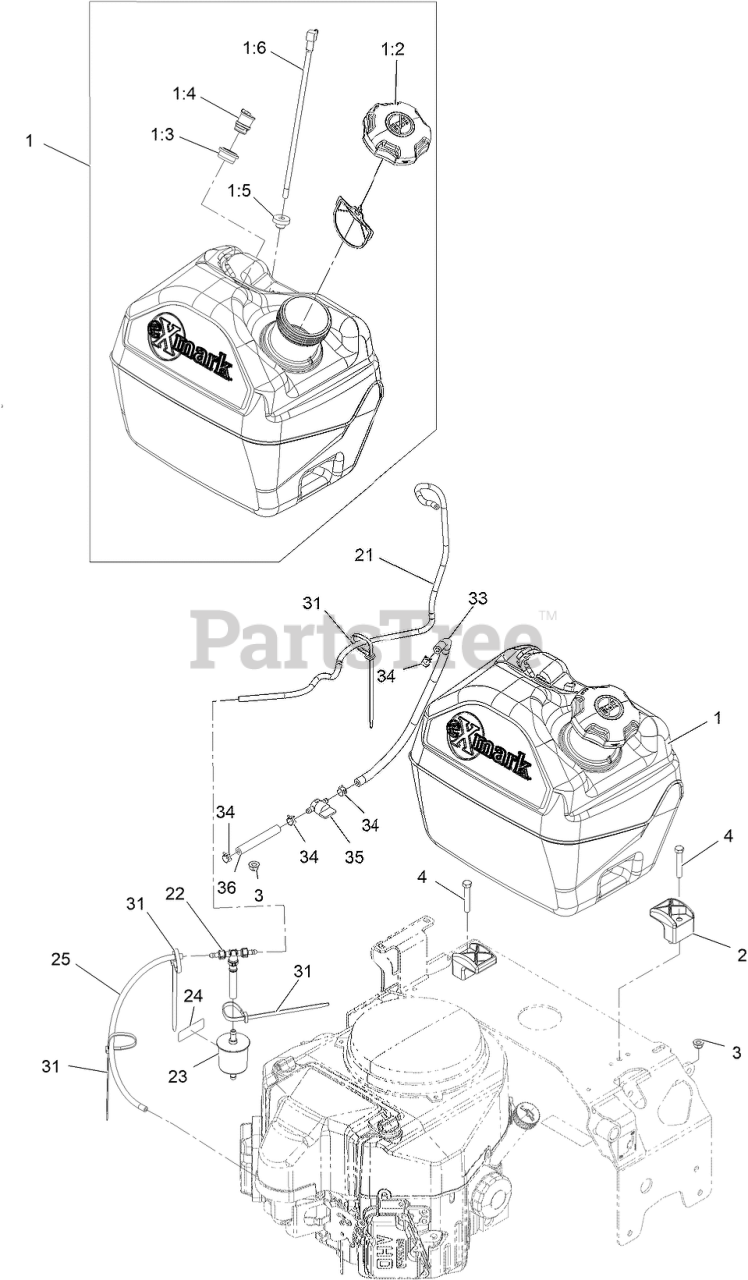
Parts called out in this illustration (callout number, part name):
1	ASM, FUEL TANK 5 GAL
1:2	CAP-FUEL, RATCHETING
1:3	GROMMET
1:4	VALVE-VENT, FUEL
1:5	BUSHING
1:6	FITTING, FUEL W/LINE AND SCREEN
3	NUT-HF, NI
4	SCREW-HH
21	HOSE, EMISSIONS
22	TEE AND CHECK
23	FILTER-FUEL
24	DECAL-FILTER, EMISSIONS
25	HOSE-FUEL
31	TIE-CABLE
33	HOSE-FUEL
34	CLAMP-HOSE
35	VALVE-FUEL
36	HOSE-FUEL
